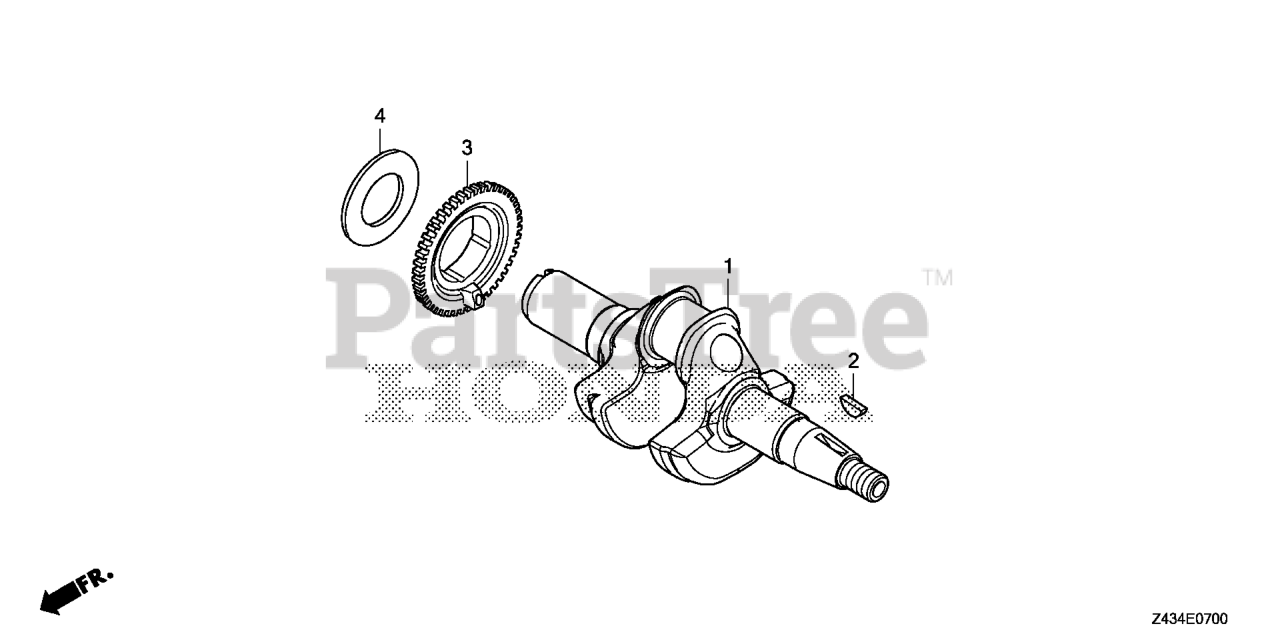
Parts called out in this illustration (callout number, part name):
1	CRANKSHAFT
2	KEY, SPECIAL WOODRUFF (25X18)
3	PULLEY, TIMING BELT DRIVE
4	WASHER, THRUST
